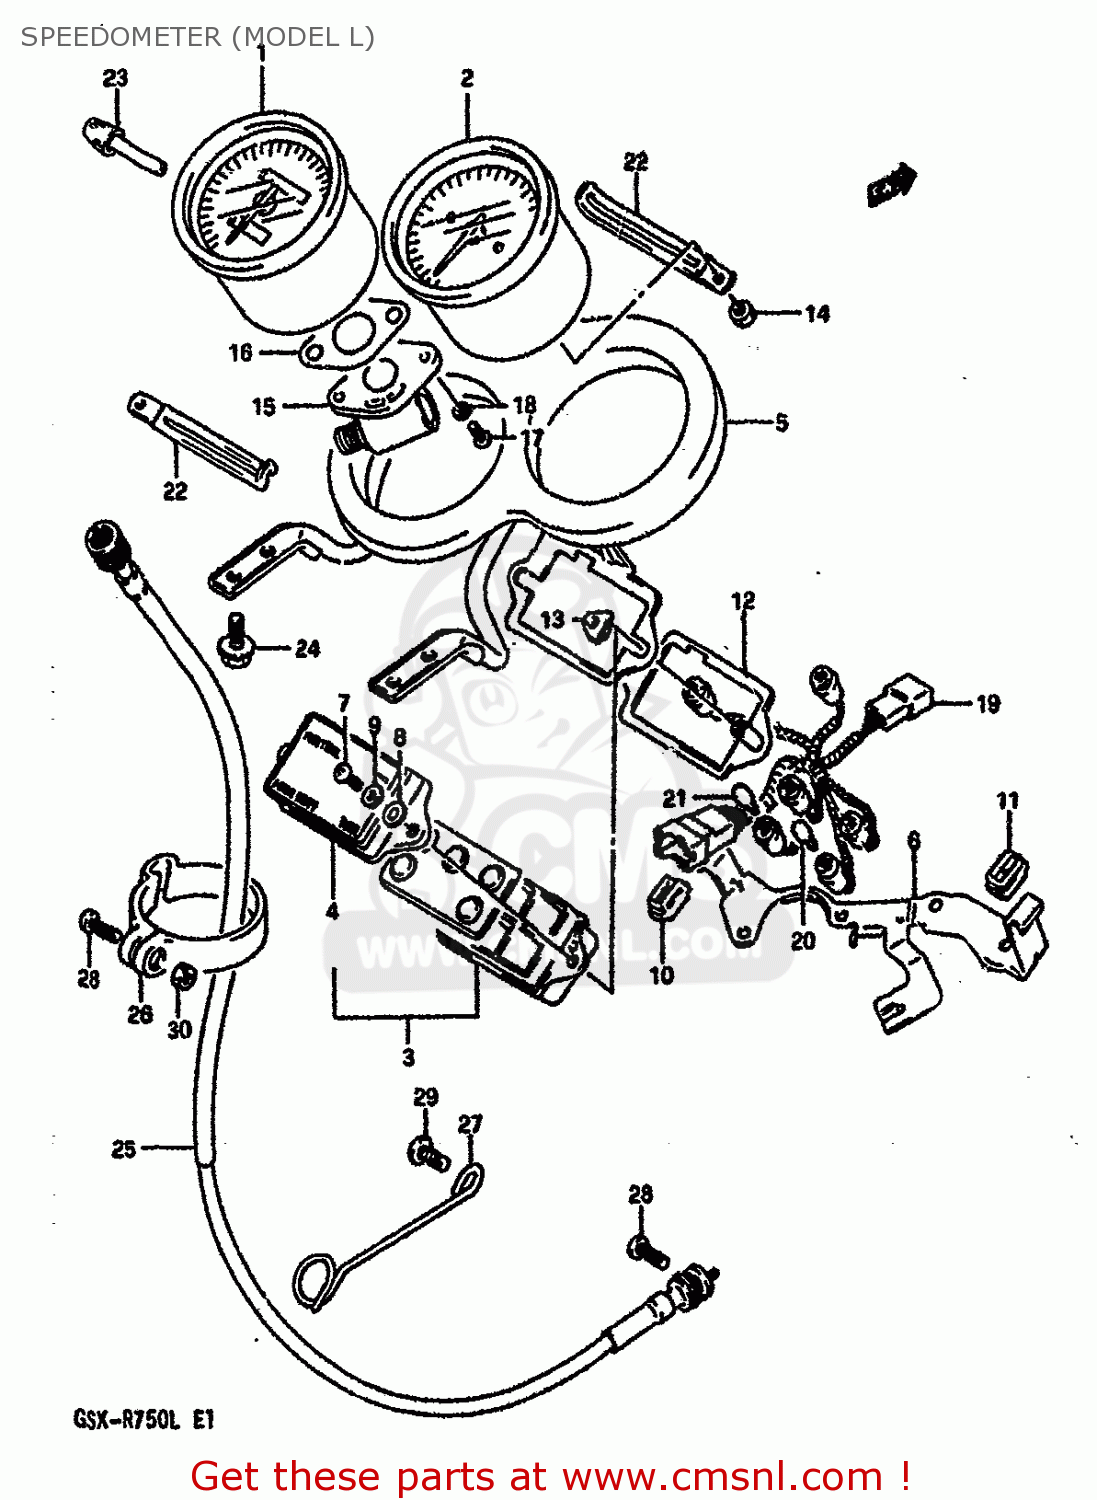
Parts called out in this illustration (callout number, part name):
1	SPEEDOMETER (KILO)
2	TACHOMETER
3	BOX,PILOT LAMP
4	CASE,UPR
5	PLATE,SETTING
6	BRACKET
7	SCREW
8	WASHER
9	WASHER,LOCK 4M
10	DAMPER,LEFT
11	CUSHION
12	PLATE,SETTING
13	DAMPER
14	NUT
15	GEAR BOX
16	GASKET,METER GEAR BOX (NAS)
17	SCREW
18	LOCK WASHER
19	SOCKET,METER
20	BULB(12V3W,T6.5)
21	BULB(12V1.7W,T6.5)
22	CLAMP
23	KNOB,TRIP
24	BOLT 6X12
25	CABLE ASSEMBLY,SPEEDOMETER
26	CLAMP,SPEEDOMETER CABLE
27	GUIDE,SPEEDOMETER CABLE NO.3
28	SCREW
29	SCREW
30	NUT
